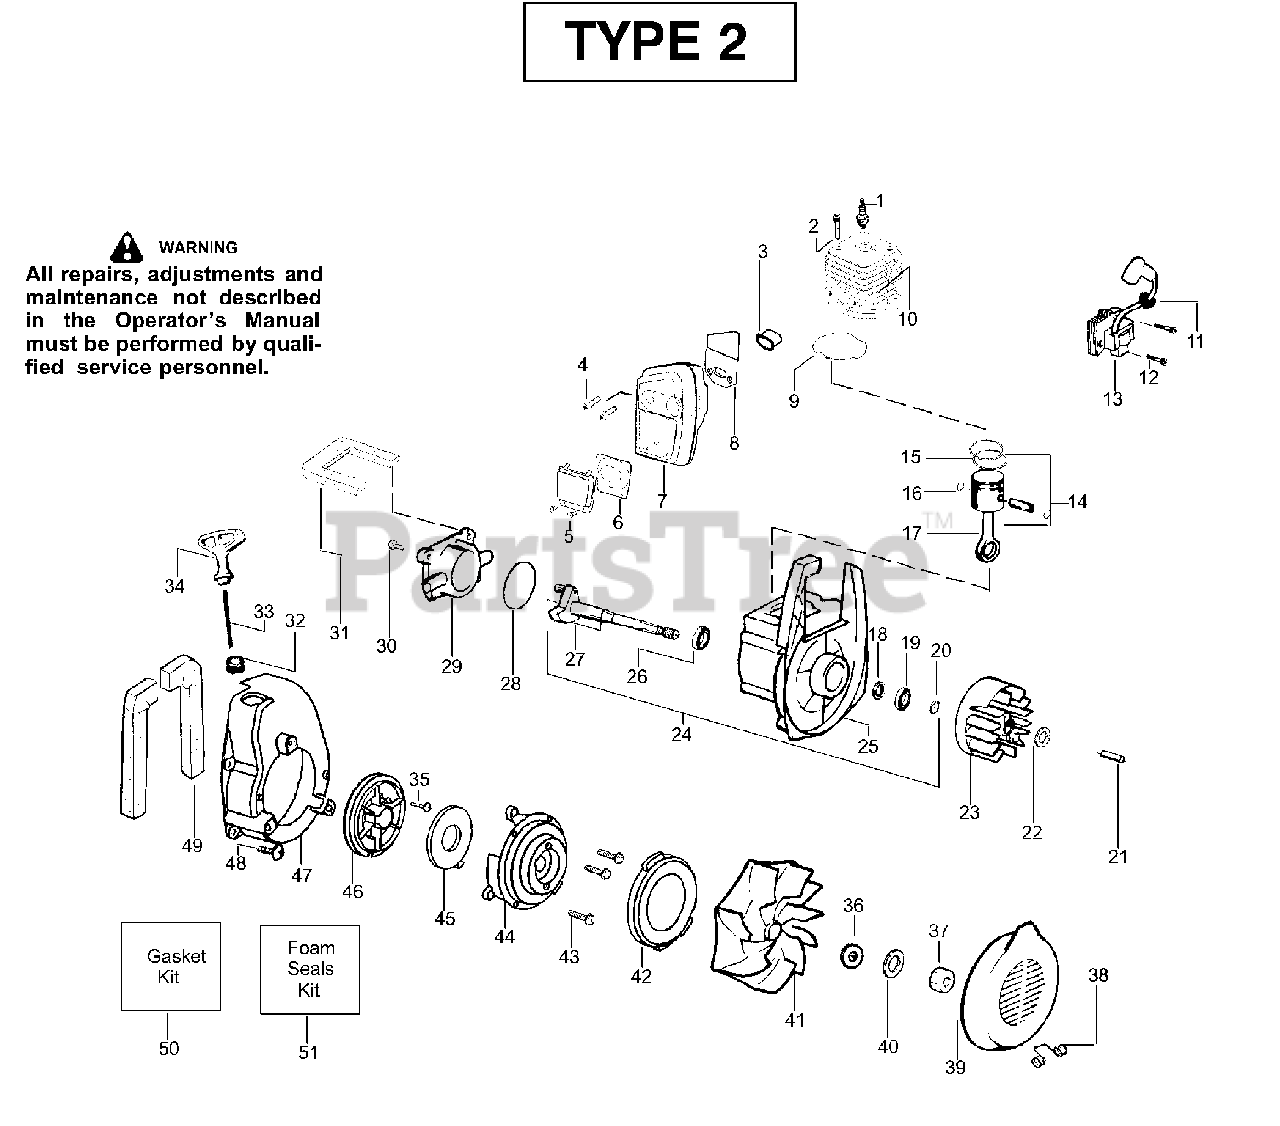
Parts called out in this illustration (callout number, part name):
1	Spark Plug (RCJ-6Y)
3	Insulator-Heat
4	Screw-Muffler-Internal
6	Kit-Spark Screen
7	Kit-Muffler
8	Gasket-Baffle (kit)
9	Gasket-Cylinder (kit)
10	Kit-Cylinder
11	Grommet-Ign. Module
12	Screw-Ignition Module
13	Ignition Module
14	Kit-Piston
15	Piston Ring
16	Retainer-Piston Pin
17	Assy-Connecting Rod
18	Kit-Crankcase Seal
19	Bearing-Outer
20	Retainer Ring-C'chaft
21	Spacer-Flywheel
23	Assy-Flywheel
24	Assy-Crankcase/Crankshaft
25	Assy-Crankcase
26	Bearing-Inner
27	Assy-Crankshaft
28	O-ring-C/case (kit)
29	Cover-Crankcase
30	Screw
31	Foam-219mm (kit)
32	Eyelet-Flange
33	Kit-Rope
34	Handle-Starter
35	Screw-Rope
36	Washer-Belleville
38	Spring-Return Cover
39	Inlet Door
40	Washer-Flat
41	Assy-Impeller
42	Seal-Ring
44	Housing-Pulley
45	Spring-Starter
46	Kit-Starter Pulley
47	Fan Housing
48	Screw
49	Foam-182mm (kit)
50	Kit-Gasket
51	Kit-Foam Seals
